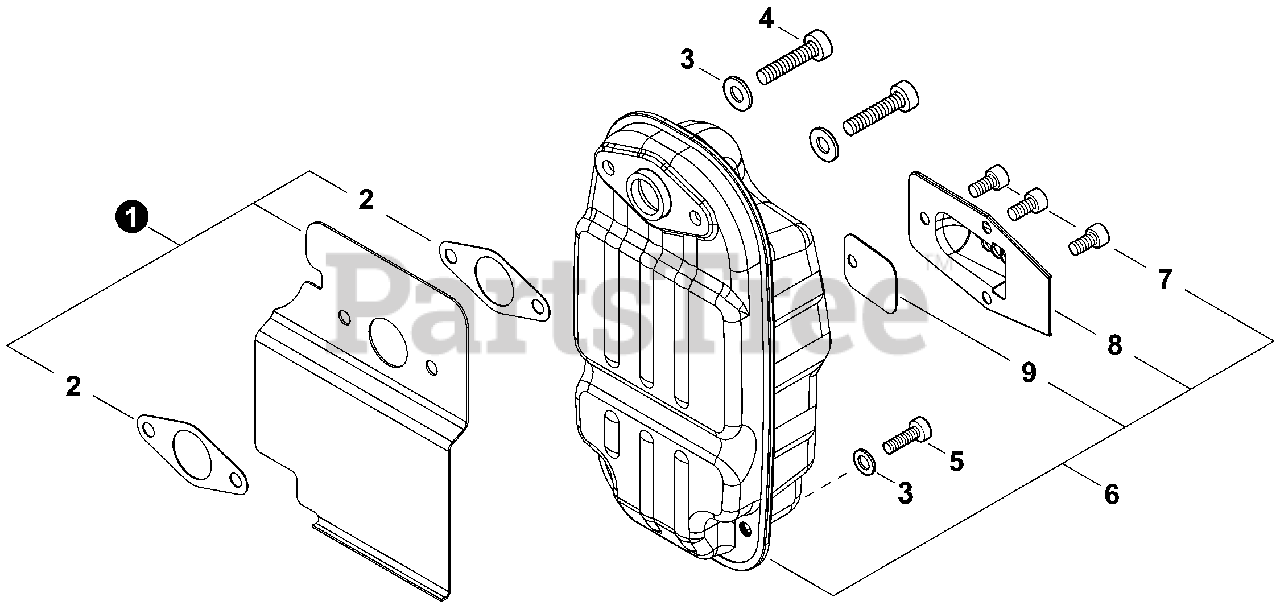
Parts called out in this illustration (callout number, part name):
1	DEFLECTOR ASSY, EXHAUST HEAT
2	GASKET, EXHAUST
3	WASHER 6.5×11.5×0.8
4	BOLT SS M6×35
5	BOLT 6×16
6	MUFFLER ASSY
7	SCREW M5×8
8	GUIDE, EXHAUST
9	SCREEN, SPARK ARRESTER
